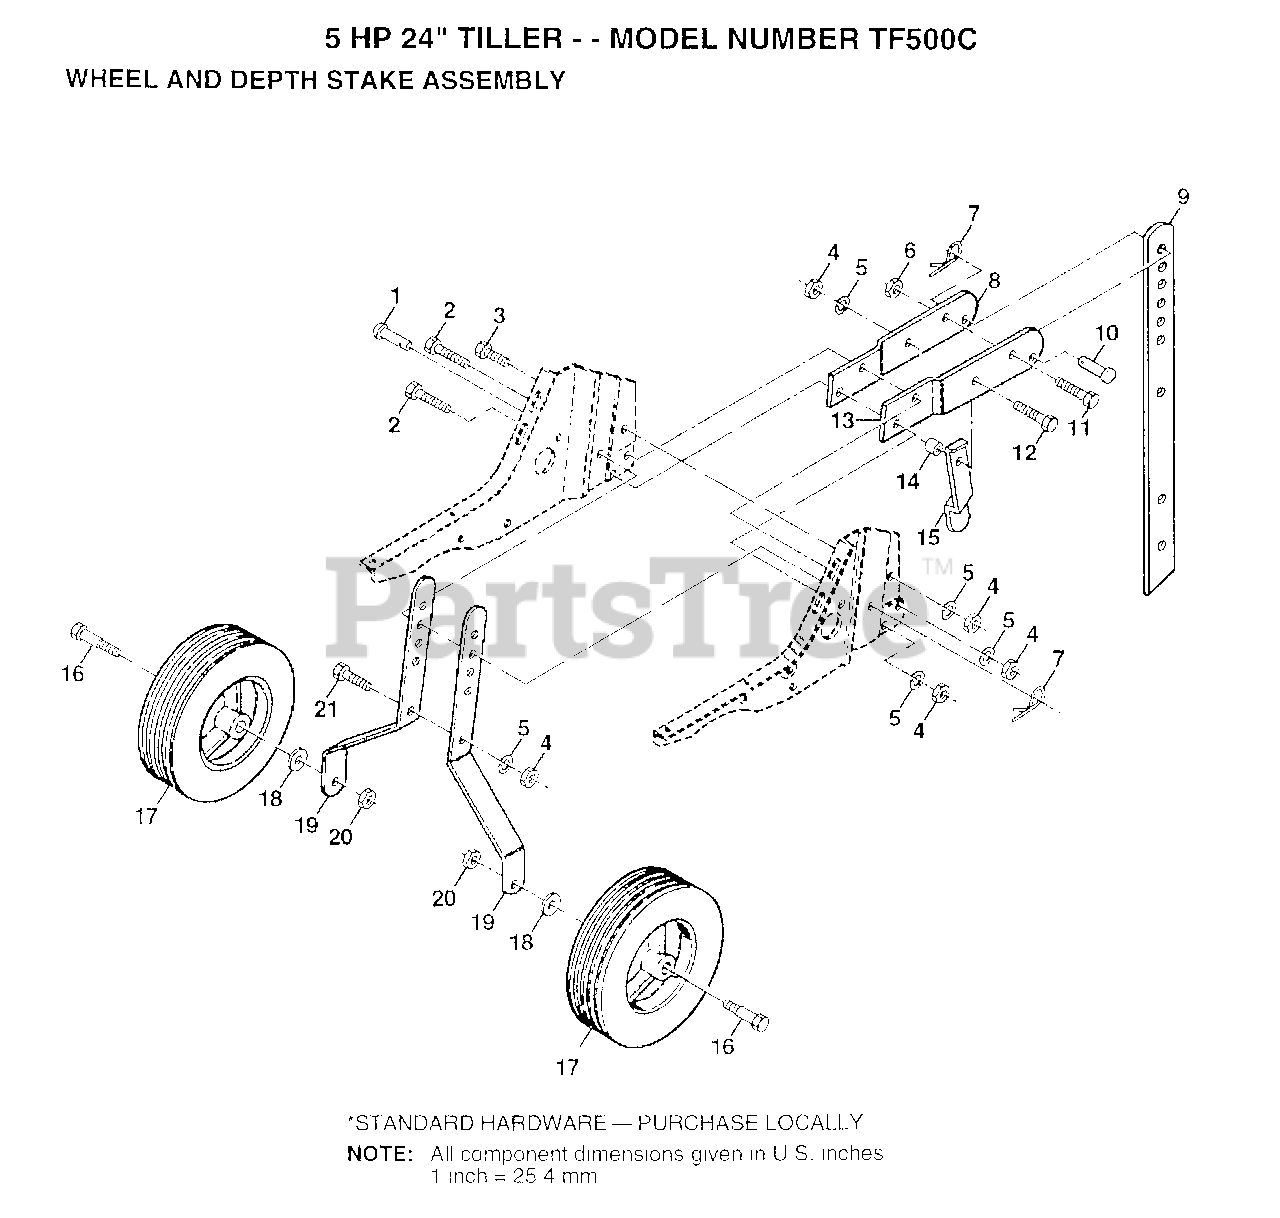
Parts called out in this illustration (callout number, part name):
1	DRILLED RIVET RT
3	BOLT
4	NUT.HEX.5/16-18
5	LOCKWASHER
6	GRIPCO NUT
7	SPRING.RETAINER
11	BOLT.3/8-24X1-1/2
12	BOLT.HEX.5/16-1.5
14	WASHER
15	STAKE SPRING TI
16	BOLT SHOULDER
18	WASHER
